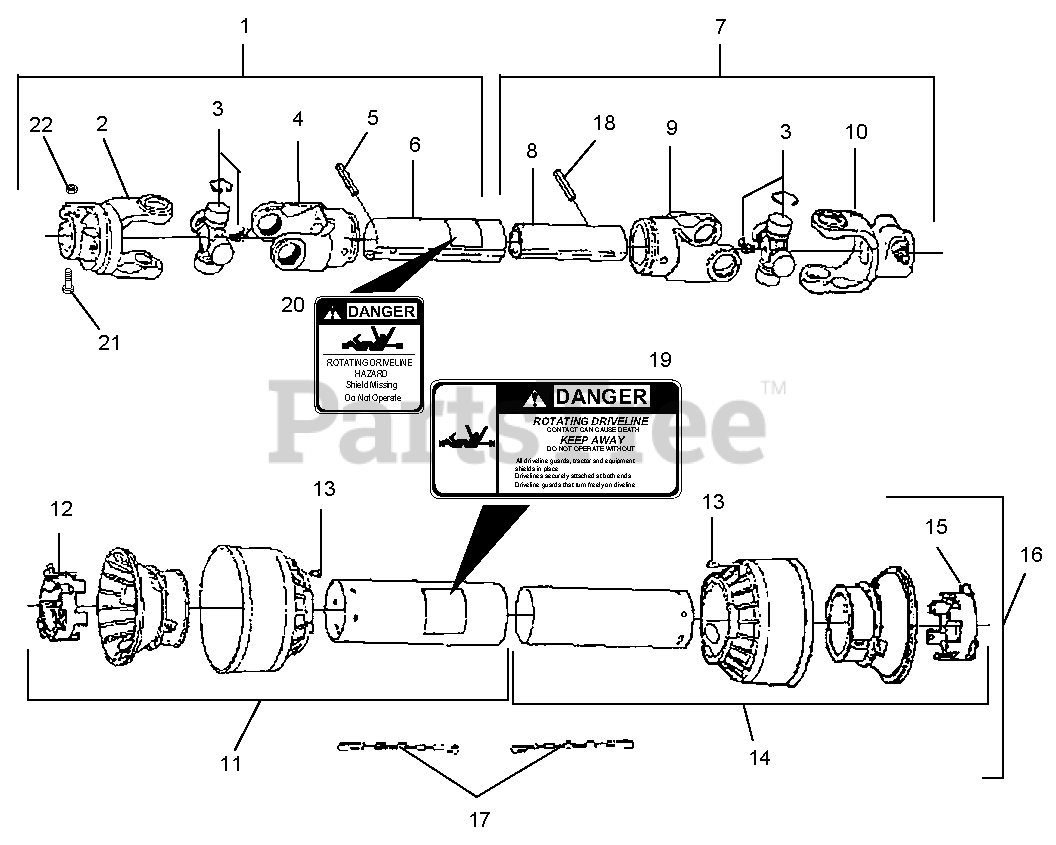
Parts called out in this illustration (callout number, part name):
1	Half Shaft, Outer
2	Assembly, Yoke
3	Cross Assembly
4	Outer Tube Yoke
5	Roll Pin 8 mm x 50 mm
6	Outer Tube
7	Half Shaft, Inner
8	Inner Tube
9	Inner Tube Yoke
10	Yoke w/Clamp Bolt
11	Half, Outer Shielding
12	Tube Bearing
13	Lock Pin
14	Half, Inner Shielding
15	Tube Bearing
16	Safety Shield (Includes 11, 12, 14 & 15)
18	Roll Pin 8 mm x 45 mm
19	Decal, Danger
20	Decal, Danger
21	Screw, Machine M6-1.0 x 40 mm HHCS
22	Locknut, Flat, ISO7043, M6-1.0
